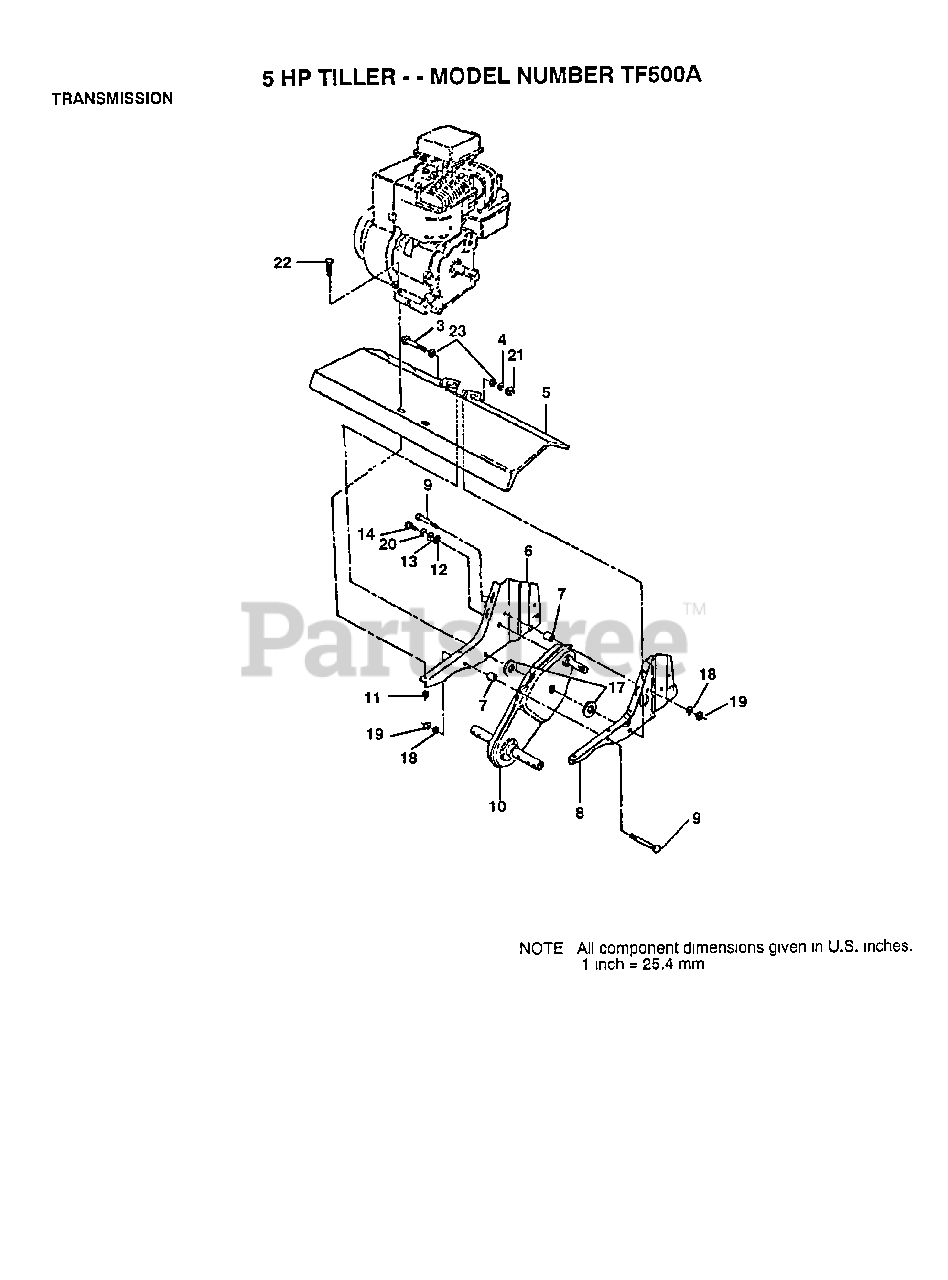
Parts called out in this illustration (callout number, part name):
3	BOLT.3/8-24X3.75
4	LOCKWASHER
7	SPLIT SPACER RT
8	BRACKET.ENG.LH.
12	WASHER
13	WASHER
14	BOLT
18	LOCKWASHER
19	NUT.HEX.5/16-18
20	LOCKWASHER
21	GRIPCO NUT
22	BOLT.HEX.5/16-1.5
23	WASHER
